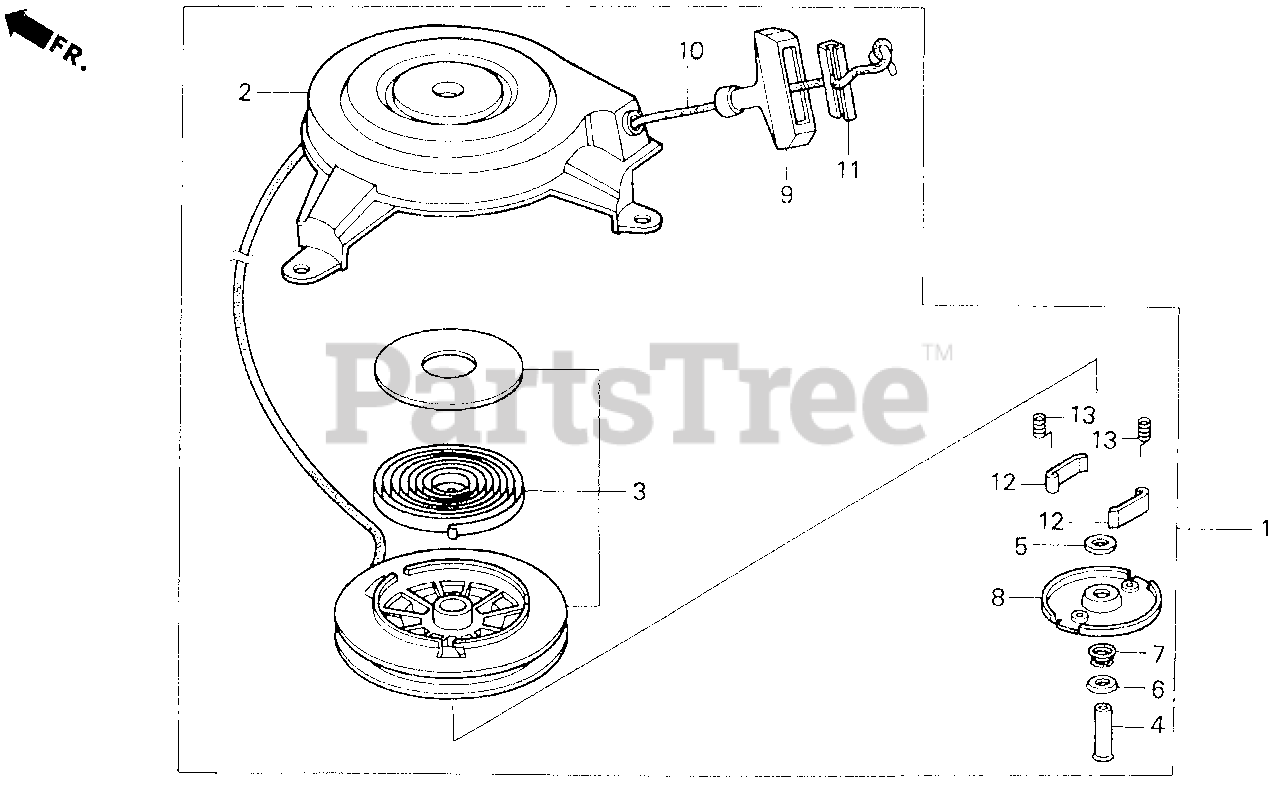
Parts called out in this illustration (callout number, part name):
1	STARTER ASSY., RECOIL
2	HOUSING ASSY.
3	PULLEY & SPRING ASSY.
4	PIN, CENTER
5	PLATE A, FRICTION
6	PLATE B, FRICTION
7	SPRING, FRICTION
8	RETAINER
9	HANDLE
10	ROPE, RECOIL STARTER
11	HANDLE, REINFORCEMENT
12	RATCHET, STARTER
13	SPRING, DOG
